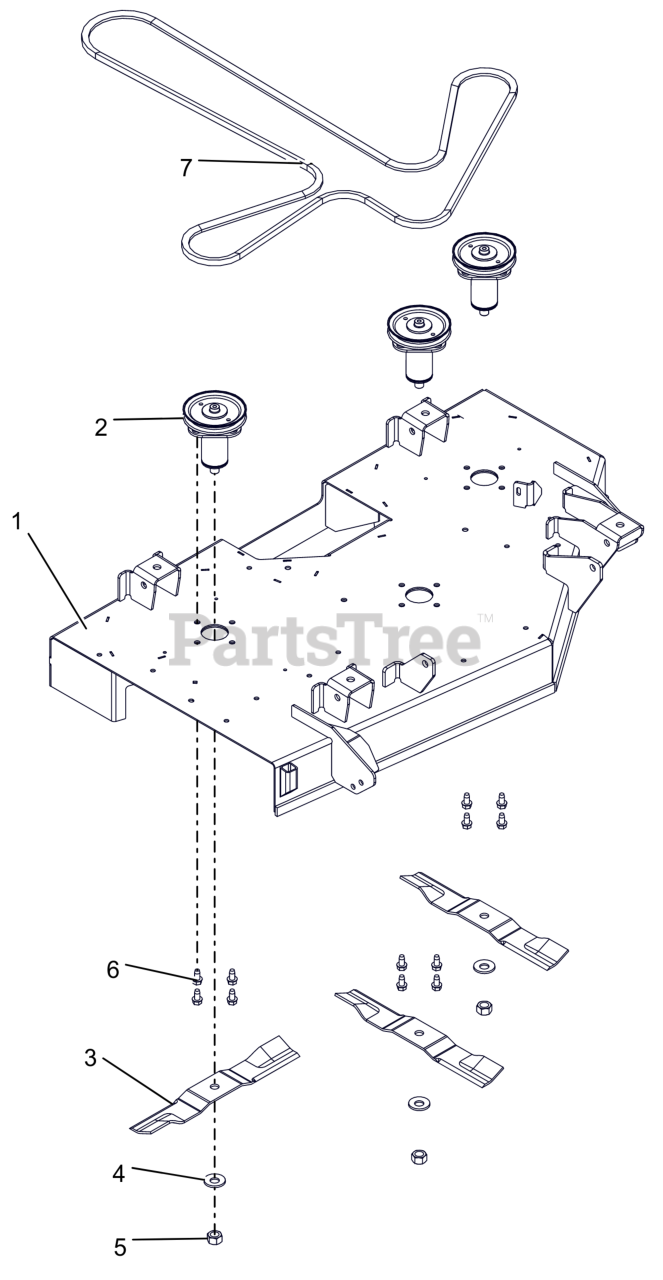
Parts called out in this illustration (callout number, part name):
1	KIT, 42" ARIENS DECK W/DECALS
2	KIT, DECK SPINDLE ASM-IKON-ZTX
3	BLADE, MOWER 15.00"
4	WSHR-BLVL .669X1.535X.138
5	NUT-STD .625-18 ZCC
6	SCR,TAP .375-16X.75 HWH TR ZCC
7	V-BELT, 4L-WRAPPED
